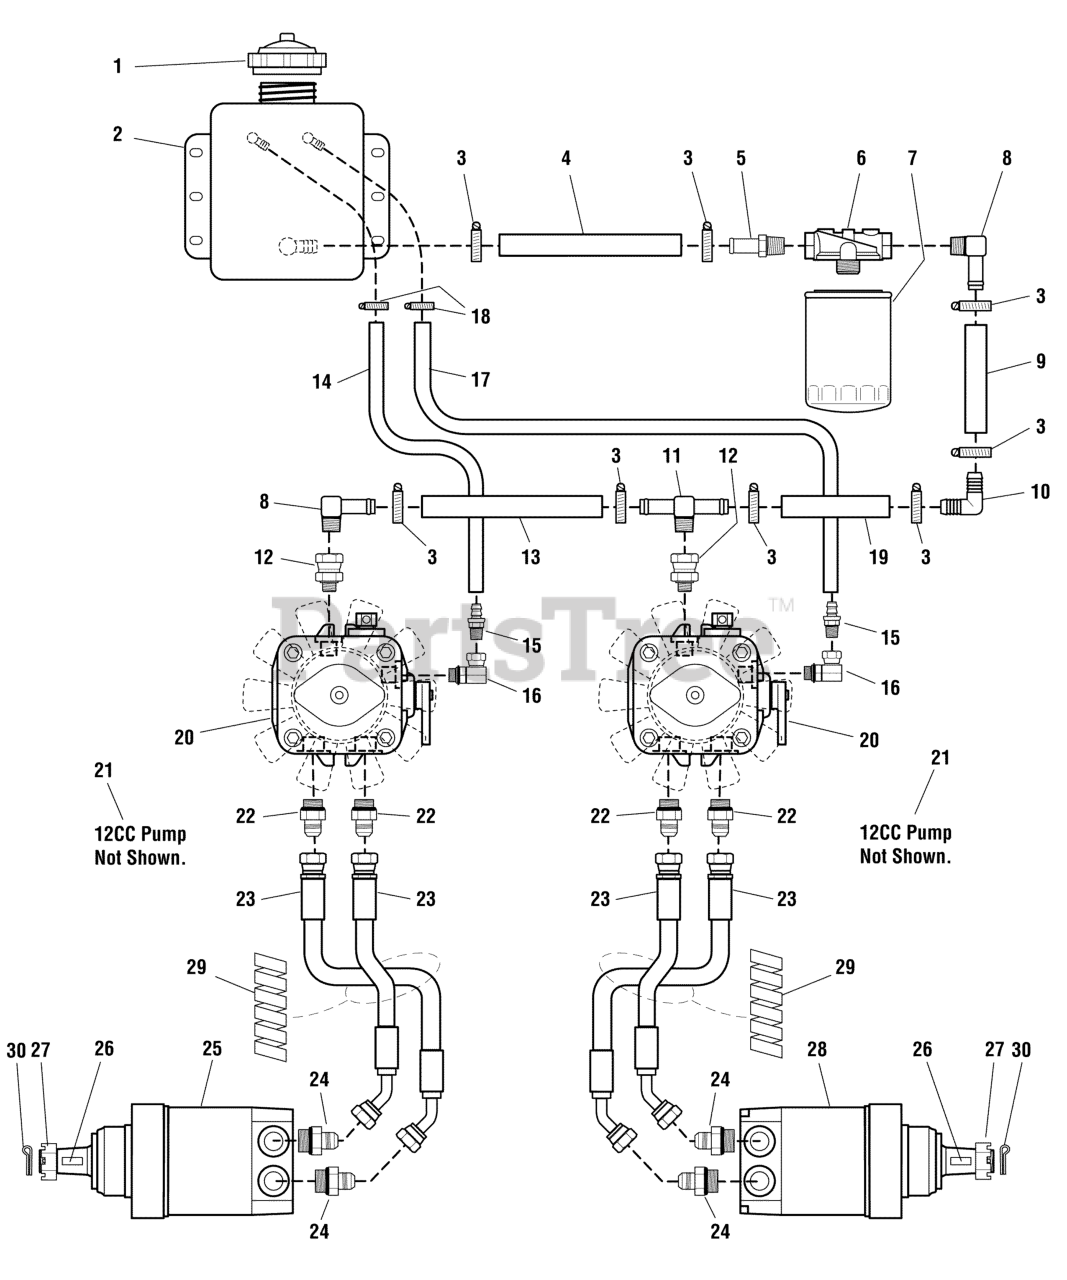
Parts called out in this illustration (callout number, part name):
1	CAP, Hydraulic Oil Only
2	KIT, TANK HYDRAULIC, 3QT W/ FITTINGS
3	CLAMP, #10 Hose
4	HOSE, Hydraulic, 11"
5	FITTING, 1/2" NPT, Straight
6	FILTER HEAD
7	FILTER, HYDRAULIC, SERVICE PART (PKG)
8	FITTING, 1/2" NPT, 90 Deg.
9	HOSE, Hydraulic, 3-1/2"
10	FITTING, 5/8", 90 Deg.
11	FITTING, 1/2" NPT, Tee
12	FITTING, Straight Swivel
13	HOSE, Hydraulic, 12"
14	HOSE, Hydraulic, 16"
15	FITTING, 1/4" NPT, Straight
16	FITTING, 9/16 O-RING - 1/4 NPT, 90 DEG
17	HOSE, Hydraulic, 24"
18	CLAMP, #6 Hose
19	HOSE, Hydraulic, 3"
20	HYDRAULIC PUMP, 10CC, w/ FAN
22	FITTING, O-Ring Adapter
23	HOSE ASSEMBLY, (33)
24	FITTING, O-Ring Adapter
25	HYDRAULIC WHEEL MOTOR-LEFT, Complete
26	KEY
27	NUT, CASTLE, 1-20
28	HYDRAULIC WHEEL MOTOR-RIGHT, Complete
29	PROTECTIVE COIL, 12"
30	PIN, COTTER, 1/8" X 2"
